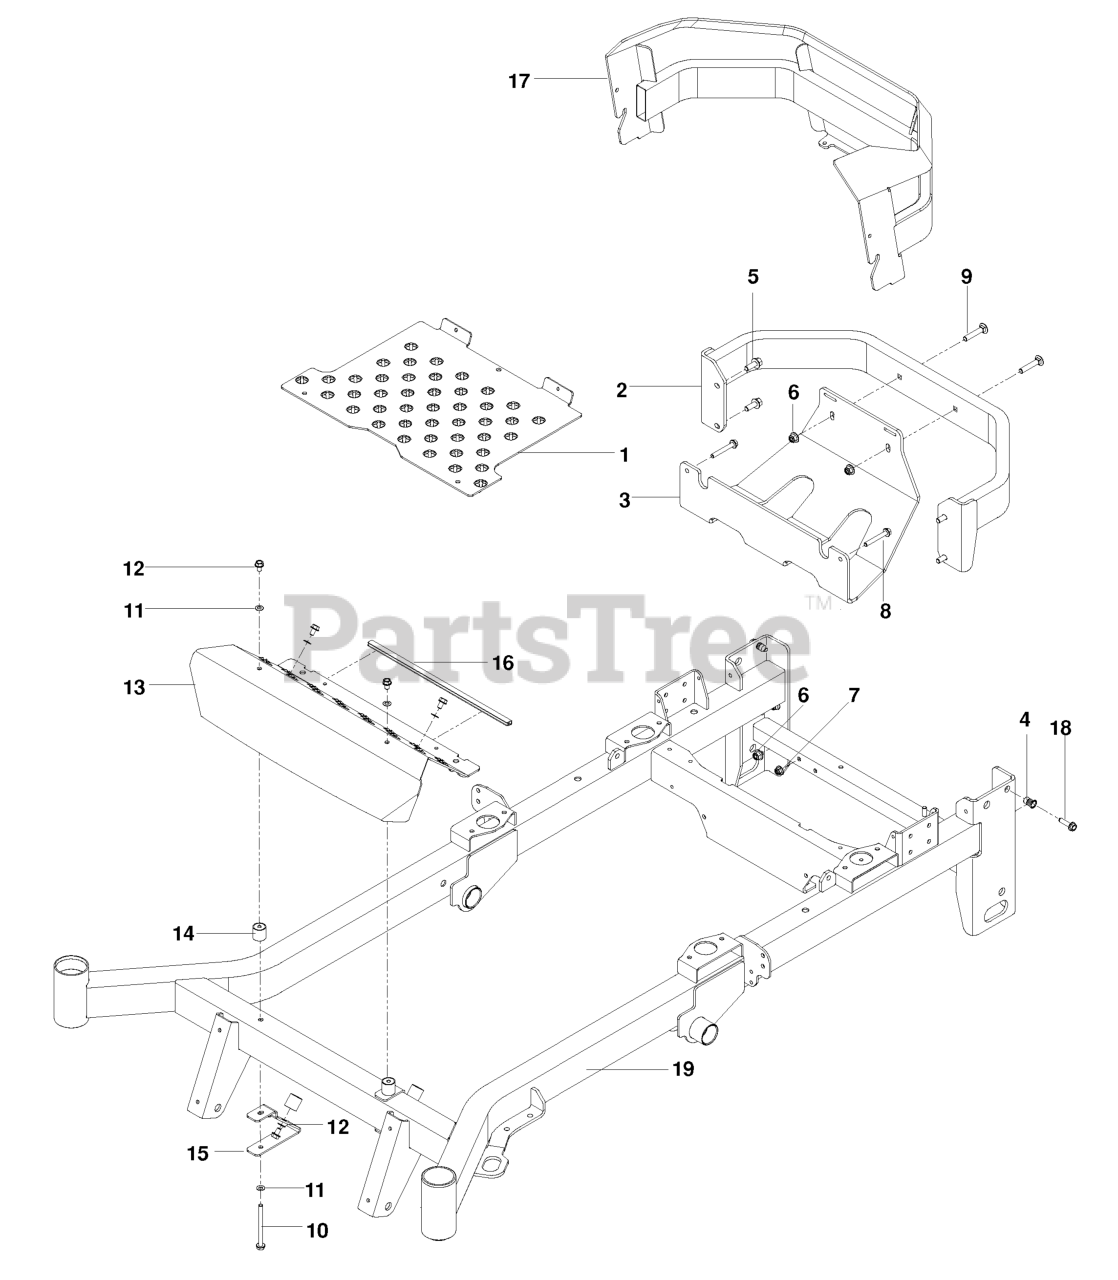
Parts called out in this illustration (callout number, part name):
1	PLATE, FLOOR PAN, OR
2	BUMPER.REAR.ORANGE
3	PLATE, SKID GRAY
4	NUTSERT 5/16-18 THICK GRIP
5	HHFS 3/8-16 X 1 GRD 5 ZD
6	NUT 3/8-16 HEX FLG NYLOC ZD
7	5/16-18 NYLOC FLANGE NUT
8	HHFS 5/16-18 X 2.25 GD 5
9	RHSNB 3/8C X 2
10	HHFS 5/16-18 X 3 3/4
11	WASH 5/16 DISC SPRING ZD
12	SCR 5/16-18 X 1/2 SELFTAP ZN
13	PLATE, FOOT REST, OR
14	MOUNT, F/F INSERT
15	BRACKET, REST MOUNT
16	RP.FLEX TRIM, BLK-LENGTH 1 FT
17	GUARD, REAR, GRAY
18	HHFS 5/16-18 X 1.25 TPBLT GD 5
19	FRAME W/DECALS, PZ
